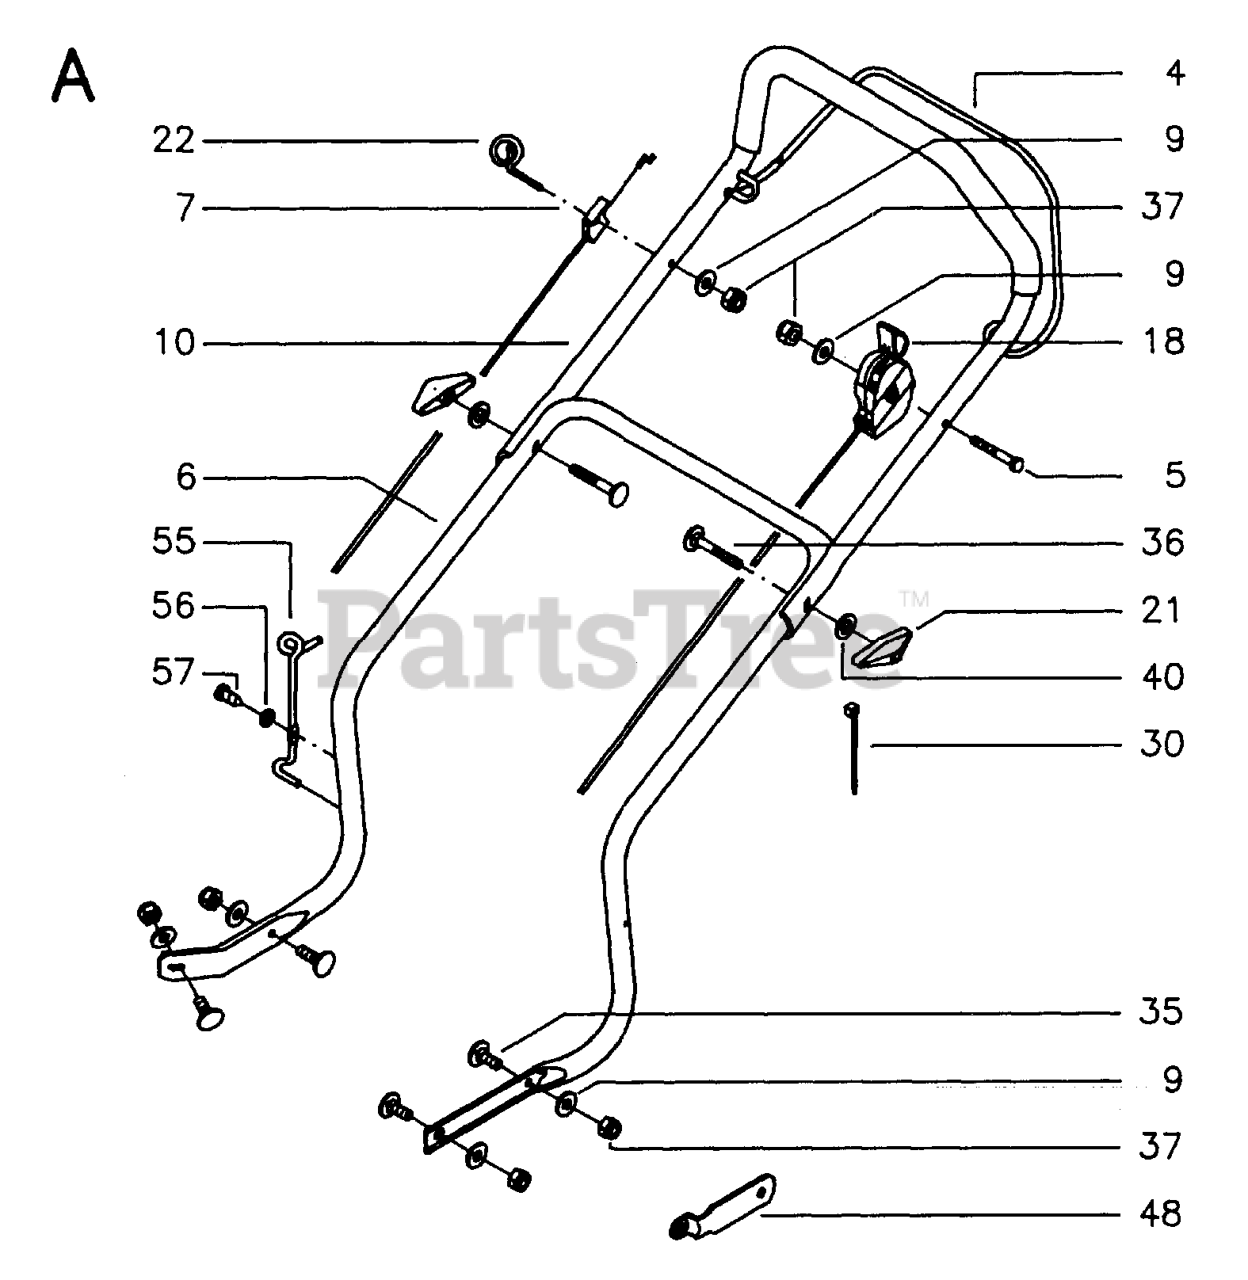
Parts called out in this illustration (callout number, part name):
18	THROTTLE TRIGGER
21	WINGNUT
37	LOCKNUT M6
40	WASHER - 15X7.3X1.6
48	REPL BY 516 61 24-00
